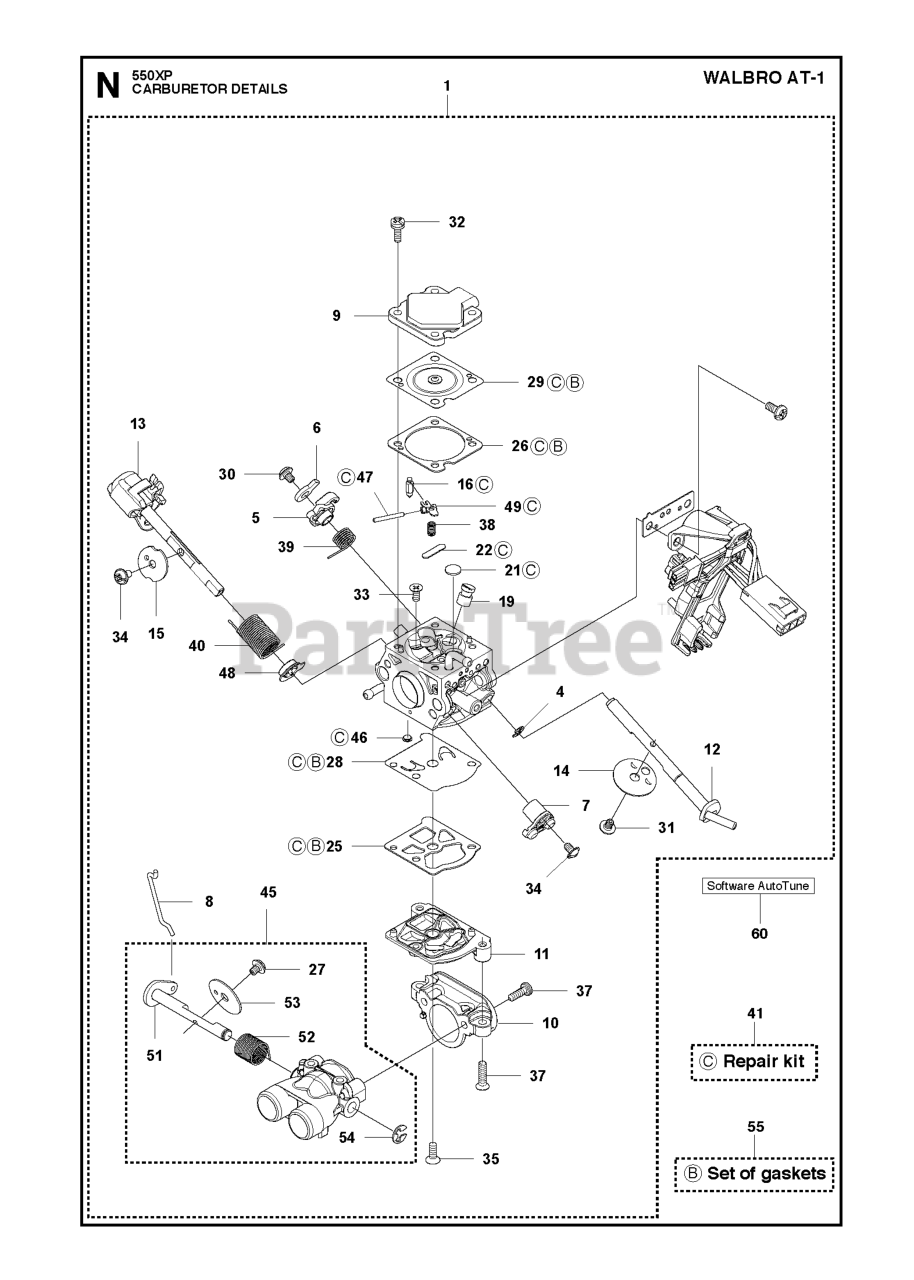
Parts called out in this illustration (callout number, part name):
1	RP CARBURETTOR
4	RETAINER
5	LEVER
6	LEVER
7	THROTTLE LEVER ASSY
8	LINK
9	COVER
10	INLET
11	COVER
12	SHAFT ASSY
13	SHAFT
14	VALVE
15	VALVE THROTTLE
16	INLET NEEDLE
19	NOZZLE ASSY
21	PLUG WELCH
22	PLUG
25	GASKET
26	GASKET
27	GASKET
28	DIAPHRAGM
29	DIAPHRAGM ASSY
30	SCREW
31	SCREW
32	SCREW
33	SCREW
34	SCREW
35	SCREW
37	SCREW
38	SPRING
39	SPRING
40	SPRING
41	REPAIR KIT
45	THROTTLE VALVE ASSY
46	FUEL INLET SCREEN
47	FULCRUM PIN
48	BUSHING
49	LEVER
51	SHAFT ASSY
52	SPRING
53	VALVE
54	E CLIP
55	GASKET KIT
60	Husqvarna TBD
